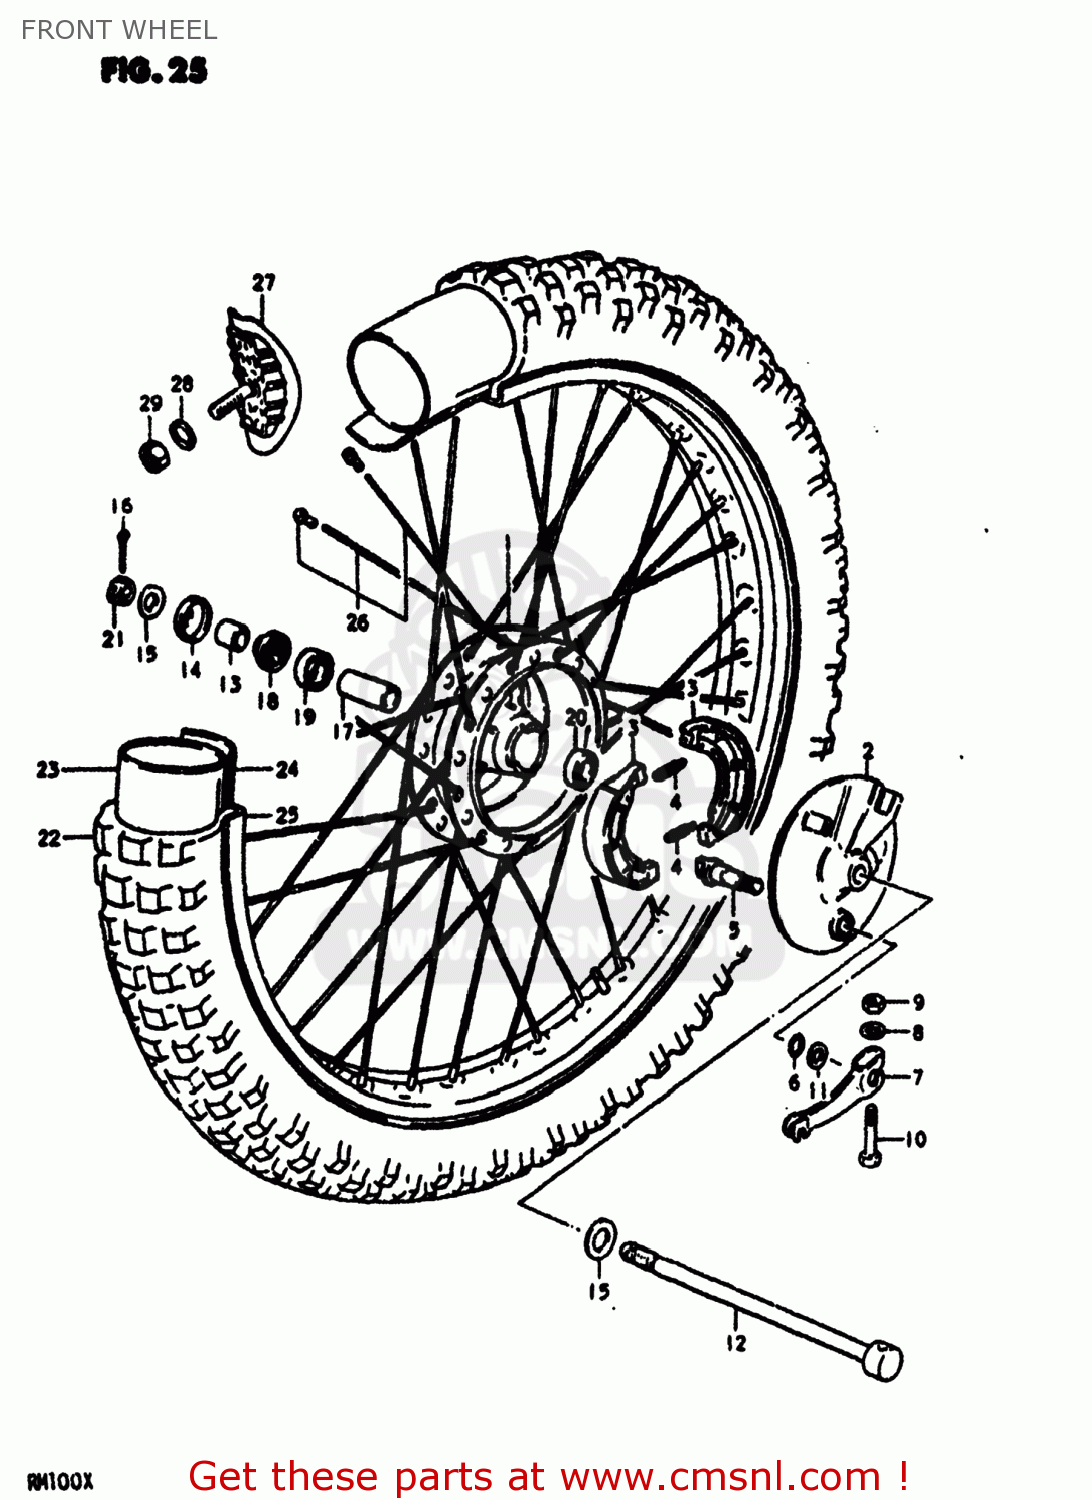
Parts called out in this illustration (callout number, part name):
1	HUB,FRONT
2	PANEL,FRONT HUB
3	SHOE,BRAKE
4	SPRING(L:34)
5	CAM,FR BRAKE
6	O RING(D:2.5,ID:11.4)
7	LEVER,FRONT BRAKE CAM
8	WASHER
9	NUT
10	BOLT
11	WASHER(12.5X20X1)
12	AXLE,FRONT
13	SPACER
14	DUST SEAL,FRONT HUB DRUM
15	WASHER
16	COTTER PIN
17	SPACER (12.6X19X52)
18	OIL SEAL
19	BEARING
20	BEARING
21	NUT 12MM
22	TIRE,FRONT
23	TUBE
24	PROTECTOR,WHEEL,INNER
25	RIM,FRONT WHEEL
26	SPOKE SET,FRONT
27	STOPPER,BEAD
28	WASHER
29	NUT
